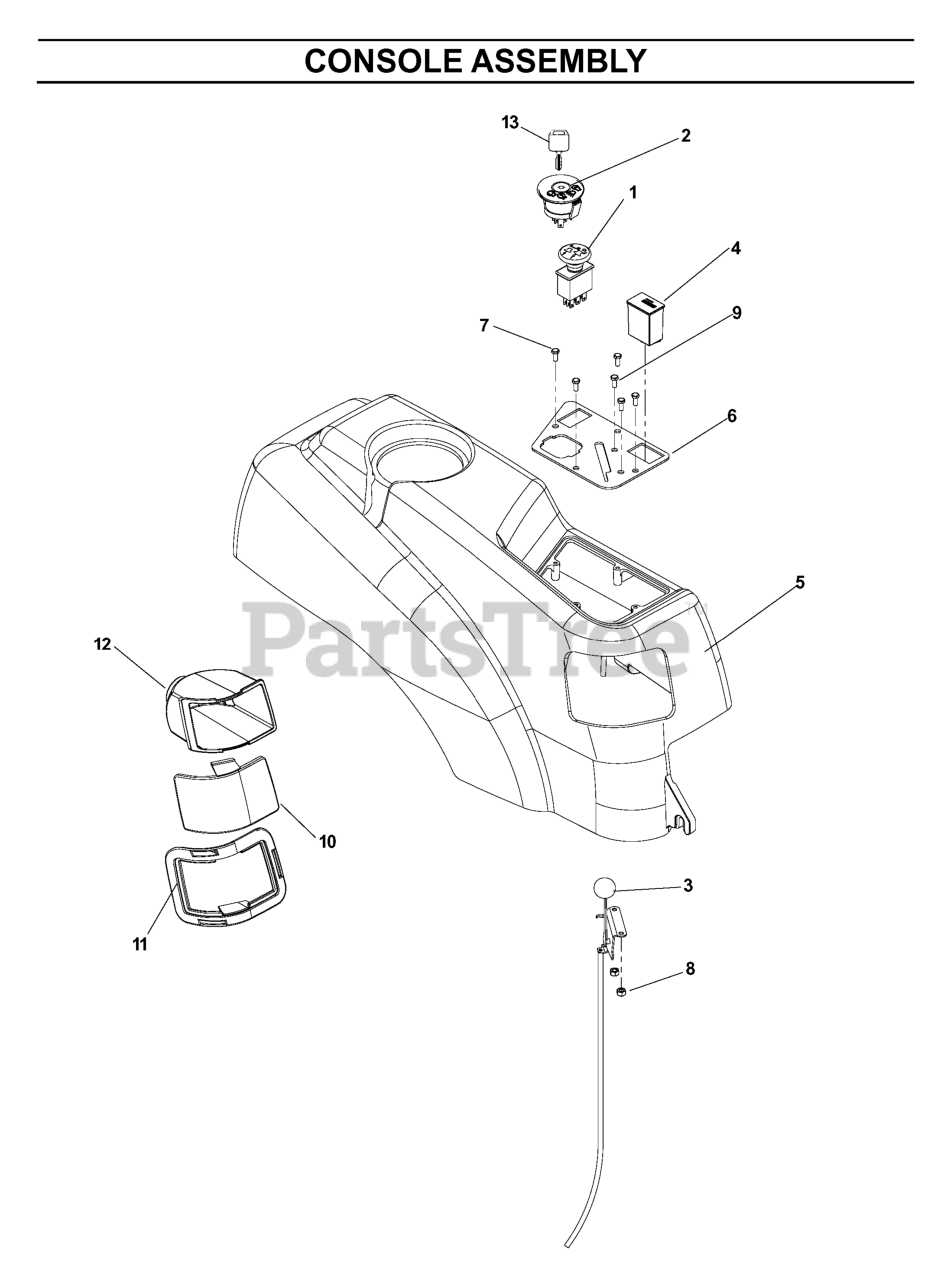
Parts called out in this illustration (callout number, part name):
1	RP.SWITCH, BLADE
2	RP IGNITION SWITCH
3	THROTTLE CABLE DETENT
4	HOUR METER
5	FENDER, CONSOLE
6	PLATE.CONTROL.CONSOLE.BLACK
7	SCR #10-12X3/4 HEX WAS HD ZD
8	NUT 10-24 NYLOC
9	HCS #10-24 X 1/2
10	LENS, COLORED LEFT
11	RT HEADLIGHT RIM GREY
12	RT HEADLIGHT REFLECTOR
13	KEY
